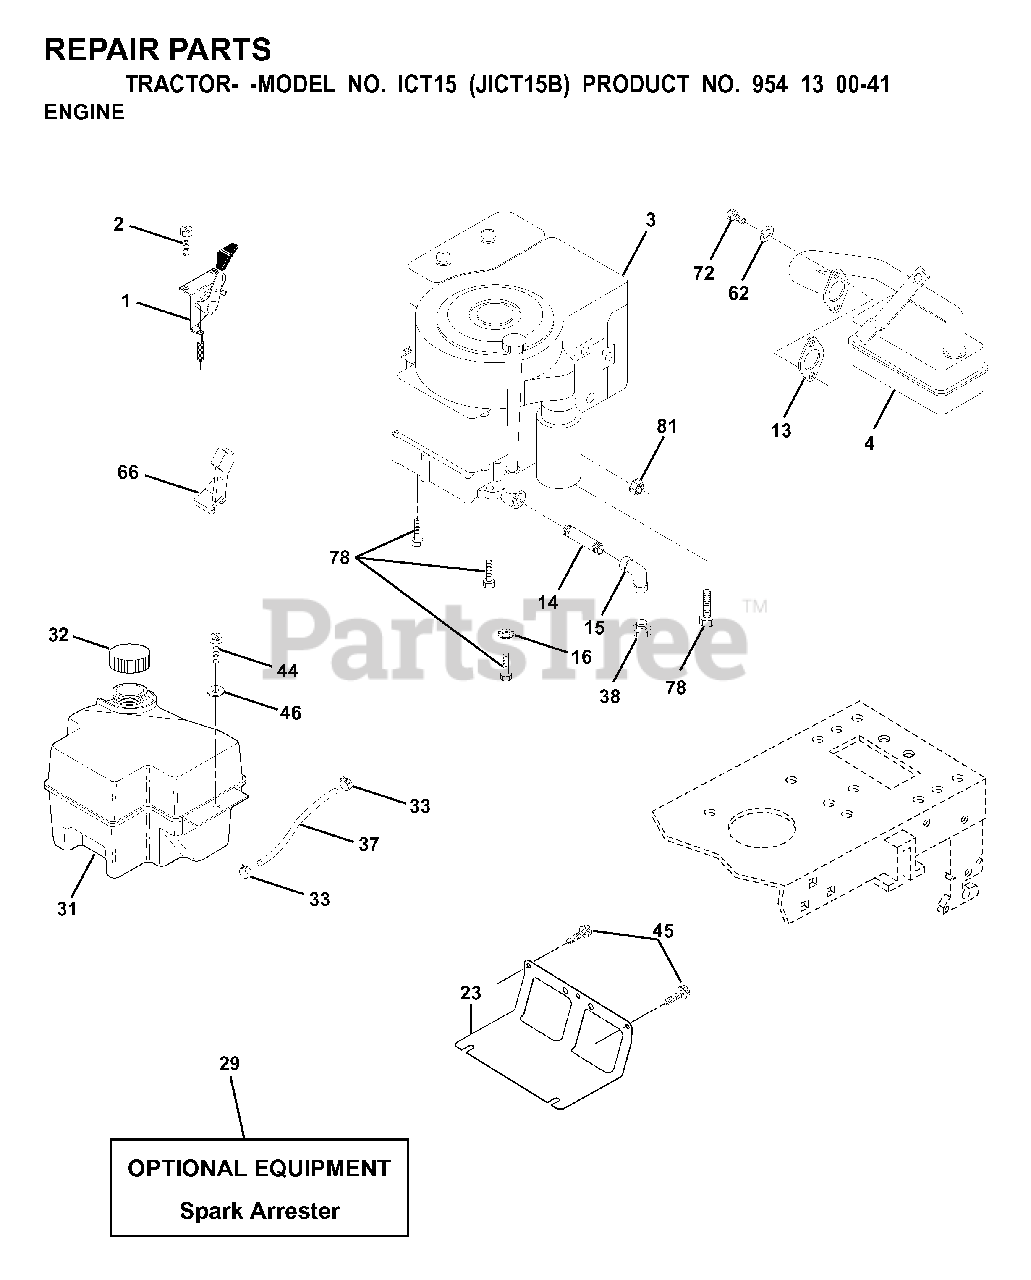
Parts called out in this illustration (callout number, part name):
1	CONTROL
2	SCREW LT
13	REPL BY 532 27 22-93
15	ELBOW
16	LOCKWASHER
23	SHEILD.BROWNING.DBR.GUARD
29	ARRESTER SPARK (OPTIONAL)
31	FUEL TANK
32	FUEL CAP
33	HOSE CLAMP
37	LINE.FUEL.20
44	SCREW HEXWSHR 1/4-20X3/4
45	SCREW, 3/8-16X3/4
62	LOCKWASHER
66	STOP THROTTLE
72	SCREW
78	SCREW.3/8-16
81	NUT
